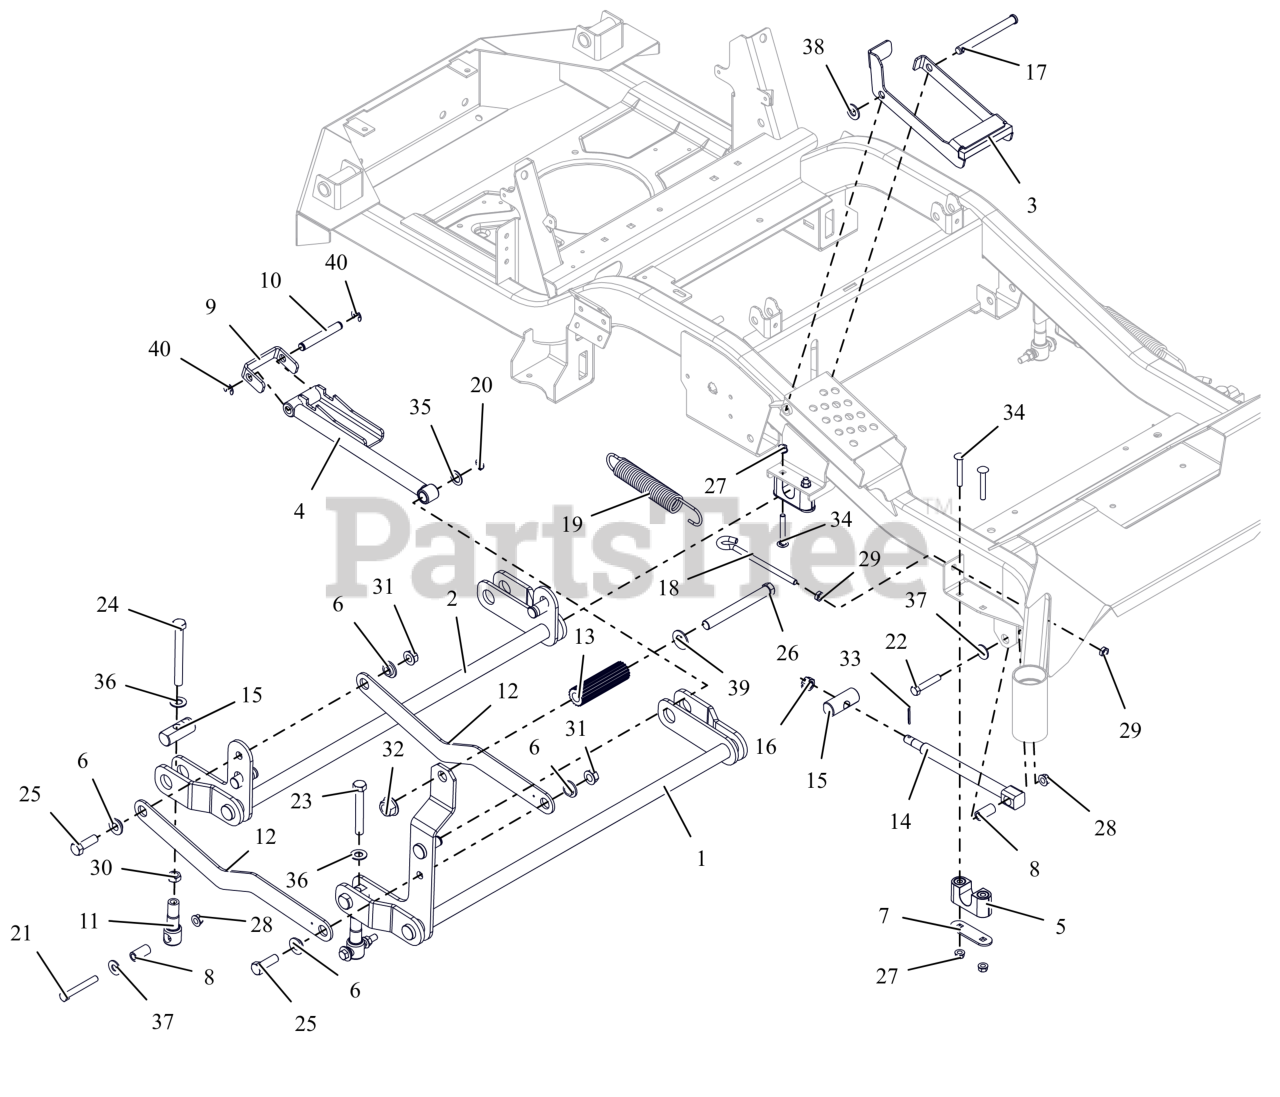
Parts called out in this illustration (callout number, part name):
1	WLDMT, FRONT DECK LIFT PIVOT
2	WLDMT, REAR DECK LIFT PIVOT
3	BRKT, HOC TRANSFER LOCK
4	WLDMT, HOC ARM
5	ASM-BUSHING, DECK LIFT
6	BSHG-FLG .515X.750X.395X1.120
7	PLATE, BEARING SUPPORT
8	SPACER, DECK LEVELING
9	BRKT, HOC LINE
10	ROD, HOC PIVOT
11	LINK, DECK LIFT FORMED
12	LINK, DECK LIFT
13	ROD, FOOT PEDAL (BLACK)
14	DRAG,LINK-HD
15	PIN, DECK LIFT
16	NUT-SL .50-13
17	PIN-SLIC .50X4.97X4.55 -ZCC
18	BOLT,.38-16 X 5.25-.62 DIA EYE
19	SG-TENS .162X1.25X8.25 WLD 25
20	RG-RTNG-EXT .625X.050
21	BLT, HEX .38-16X2.75 G8 ZCC
22	BLT,HEX .38-16X2.00 G5 ZCC
23	BLT, HEX .50-13X3.50F G5 ZCC
24	BLT, HEX .50-13X4.50F G8 ZCC
25	BLT,HEX .50-13X1.50 G5 ZCC
26	BLT, HEX .62-11X5.50 G5 FBP
27	NUT,LK-CTR-FLG .31-18 GF ZCC
28	NUT-LK-TOP-FLG .38-16 ZC120
29	NUT-JAM .375-16 G2 ZCC
30	NUT-JAM .500-13 G2 ZCC
31	NUT-LK-TOP-FLG .500-13 GF ZCC
32	NUT,FLG-TOP LK .625-11 FBP
33	PIN,CTR.12X1.25EXTPRSQCT ZC120
34	BLT, RHSSN.31-18X2.25 G5 ZCC
35	WSHR, FLT .630X1.005X.062 ZCC
36	WSHR, FLT .557X1.040X.102 ZCC
37	WSHR,FLT .438X1.00X.083 ZCC
38	WSHR,FLT .531X1.062X.095 ZCC
39	WSHRFLT 5/8SAE CARBHARD FBP
40	RG-RTNG-EXT .500X.042 (E)
